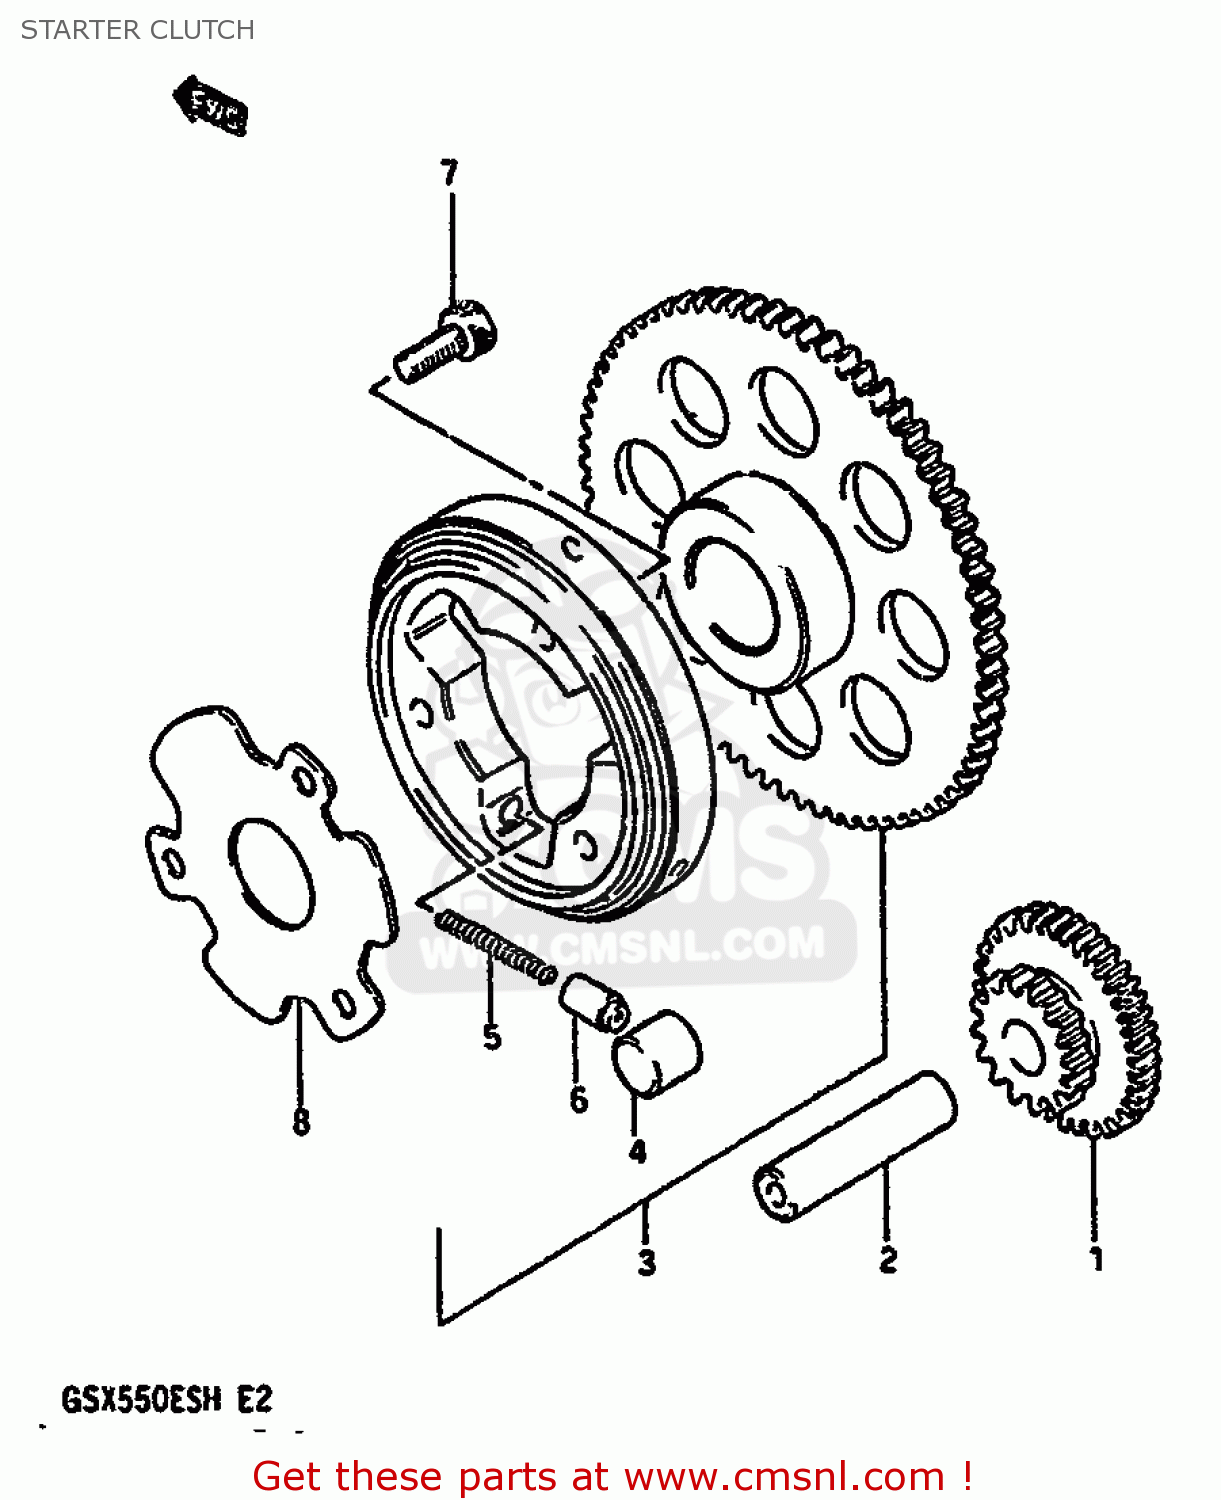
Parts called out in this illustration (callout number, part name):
1	GEAR,STARTER IDLE
2	PIN(7.4X13X56)
3	CLUTCH SET,STARTER
4	PIN(14X13)
5	SPRING
6	PIECE,PUSH
7	BOLT
8	SHIM,STARTER CLUTCH HUB
